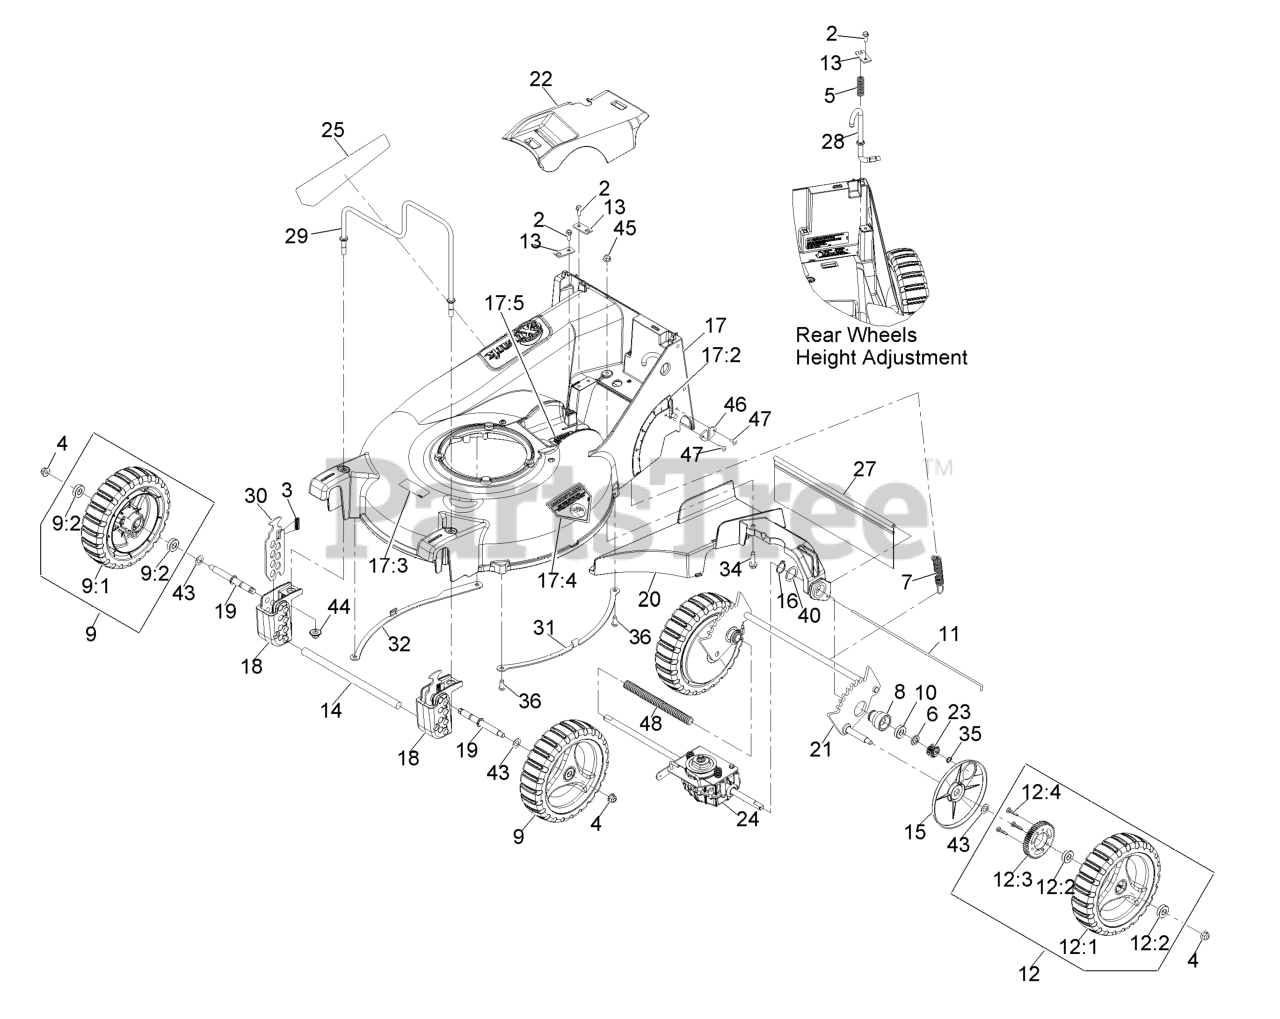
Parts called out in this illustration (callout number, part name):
2	SCREW-HWH
3	SPRING-COMPRESSION
4	NUT-HF, NI
5	SPRING-COMPRESSION
6	SPACER-BUSHING
7	SPRING-EXTENSION
9:2	BEARING-BALL
10	BEARING-BALL
11	ROD,SHIELD
12:2	BEARING-BALL
12:4	SCREW-DRIVE
13	BRACKET,MOUNT
14	ROD,BUMPER
15	COVER,GEAR
16	RING-RETAINING
17	DECK W/DECALS
17:2	DECAL-HEIGHT OF CUT
17:3	DECAL-BLADE
17:4	DECAL-DANGER
17:5	DECAL-COVER MISSING
18	BLOCK,FRONT QUADRANT
19	AXLE-WHEEL
21	WLD,REAR AXLE P21
22	COVER,BELT
24	ASM,TRANSMISSION W/BRACKE
25	DECAL-COMM 21 X-SERIES
27	SHIELD-TRAILING P21
28	ROD-HEIGHT ADJ P21
29	GUARD,ENGINE
30	PLATE, FRONT HEIGHT
34	SCREW-HWHTF
35	RING-RETAINING
36	SCREW-BHTF
43	WASHER-PLAIN
44	Nut-Nyloc 3/8-16 Flg
45	NUT-HF, NI
46	PLATE,WEAR
47	RIVET-BLIND
48	COVER-SHAFT, DRIVE
